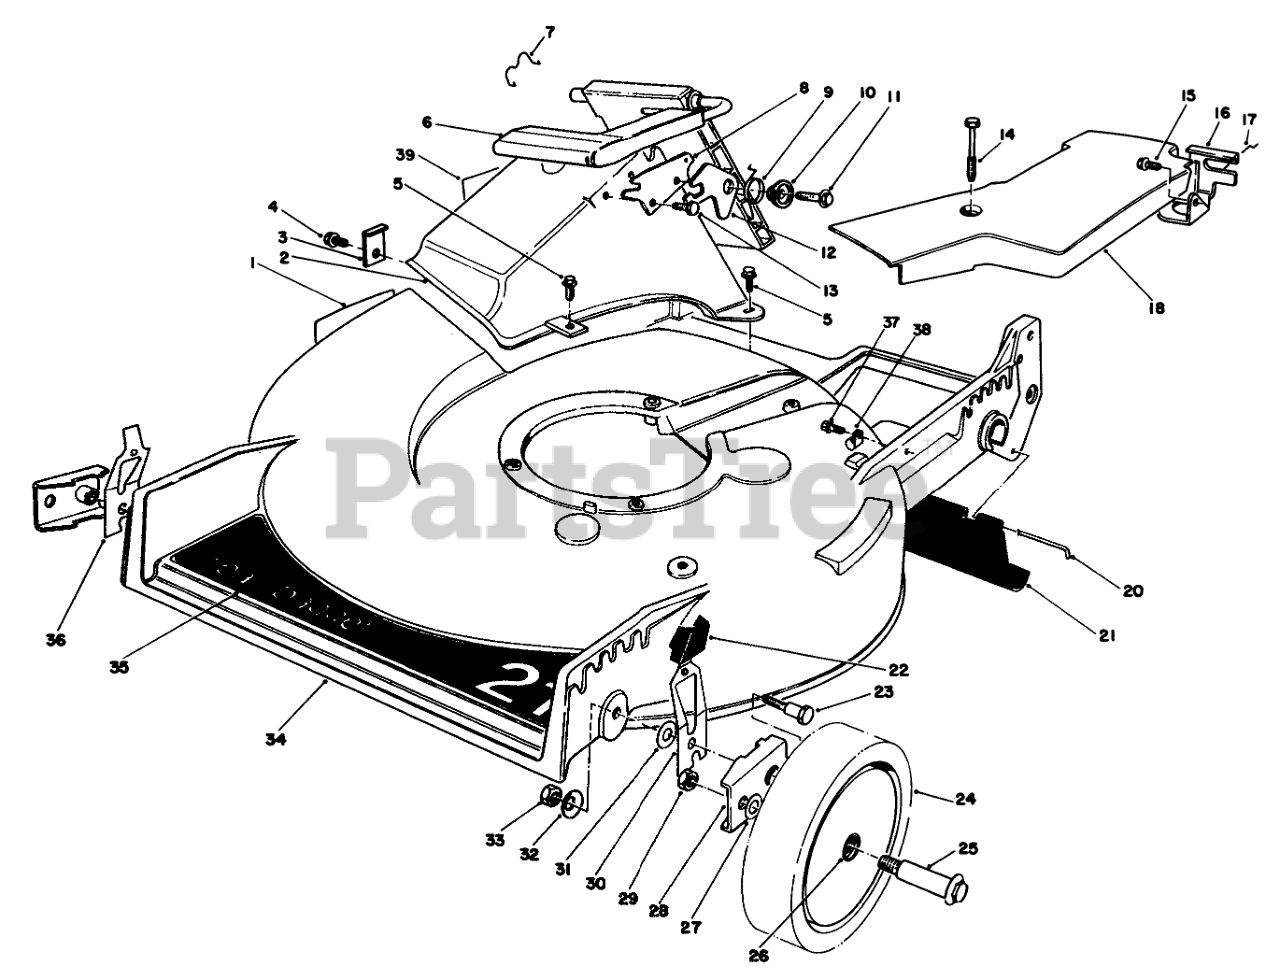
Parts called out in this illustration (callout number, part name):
1	DECAL-DANGER
2	Tunnel-Discharge (Incl. Ref. #39)
3	TUNNEL CLIP
4	SCREW
5	SCREW-HWH
6	Discharge Door Assembly
7	DOOR RET SPRING
8	DOOR LATCH PLATE
9	TORSION SPRING
10	DOOR SPACER
11	SCREW-HWH
12	SAFETY LATCH
13	SCREW-PLASTITE
14	SCREW-HHFTF
15	SCREW-HWHTF
16	Bracket-Traction Adj.
17	RETAINER-CABLE
18	Belt Cover
20	ROD-SHIELD
21	SHIELD-TRAILING
22	KNOB-ARM
23	PIVOT SCREW
24	Wheel & Tire Assembly (Incl. Ref. #26)
25	BOLT-WHEEL
26	BUSHING
27	WASHER
28	HP PIVOT ARM ASM
29	Nut
30	L. HP SPRING ARM ASM
31	WASHER-PIVOT
32	WASHER-BELLEVILLE
33	NUT-LOCK, NI
34	Housing (Incl. Ref. #1)
35	DECK DECAL
36	R HP SPRING ARM ASM
37	SCREW
38	CLAMP-CABLE
39	DECAL-DANGER
